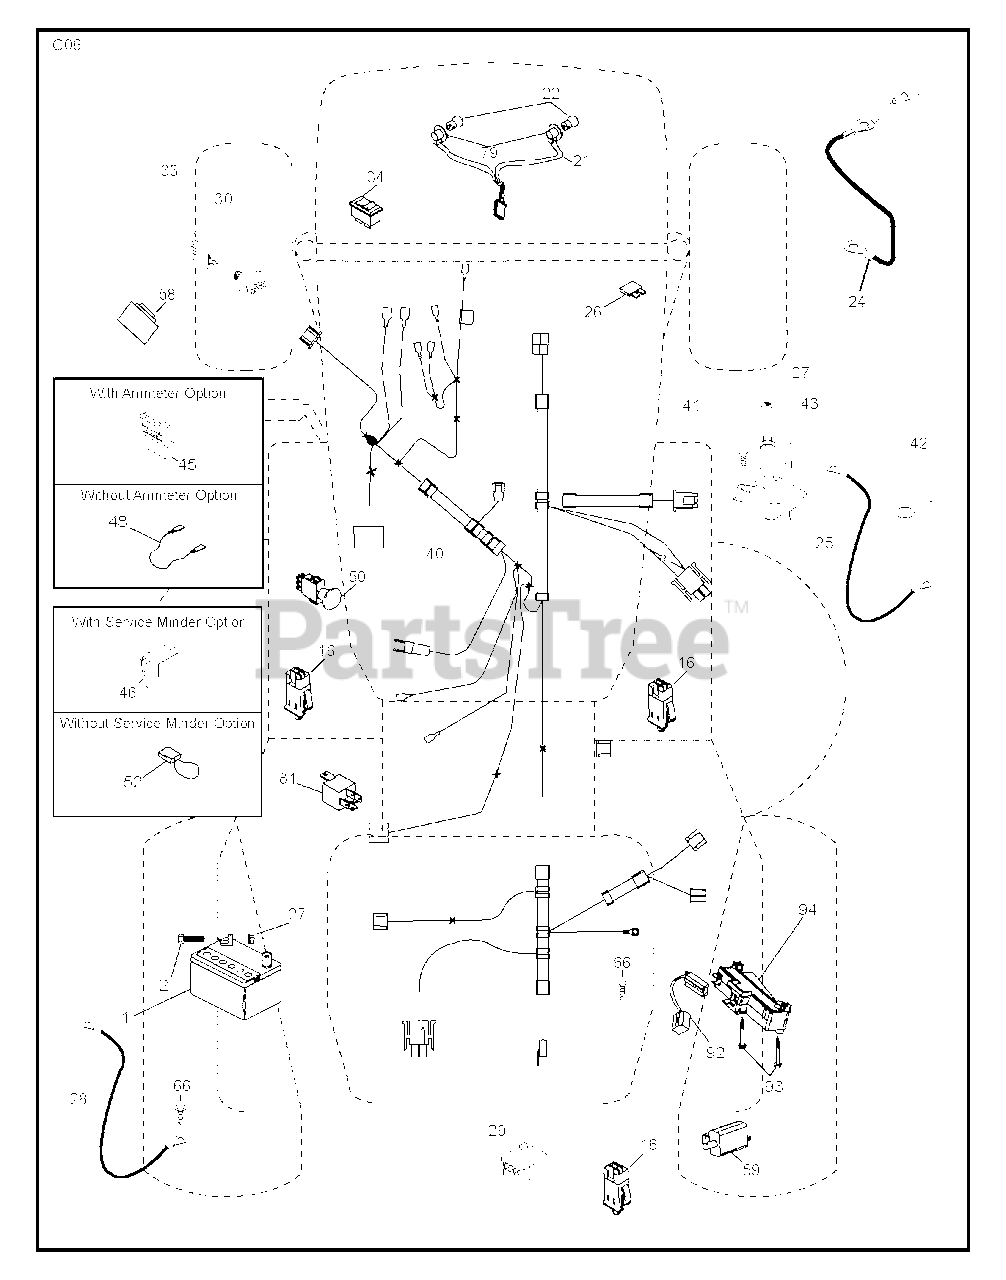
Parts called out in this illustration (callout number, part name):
1	Battery, Dry 30 Amp
2	BOLT.HEX.1/4.X.3/4.DICHROMATE
16	SWITCH INTERLOOK PUSH-IN
21	HARNESS.LIGHT W/4152J BULBS
24	CABLE BATTERY
25	CABLE.STARTER.6GA.11"RED
26	FUSE 20AMP
27	NUT
28	CABLE GROUND
29	SWITCH.SEAT.DP W/RAMPS
30	SWITCH.IGN.DELTA.W.LGH.ROS
33	KEY.CHAIN.BLISTER.PACK.GEN.INT
40	RP HARNESS.IGN.ELECT.REG.CRD
41	BOLT
42	TERMINAL COVER
43	SOLENOID.W/BRASS.PLUNGER
48	ADAPTER.AMMETER
50	RB PTO.SWITCH.8 TERMINAL.BLACK
58	BUZZER
59	.WITCH.FULL BAGGER.INDICATOR
79	BULB HOLDER ASM.
81	RELAY.ASSY.T
92	HARNESS.PIGTAIL.CONSLE
93	SCREW.PLASTITE
94	MODULE.REVERSE.ROS
